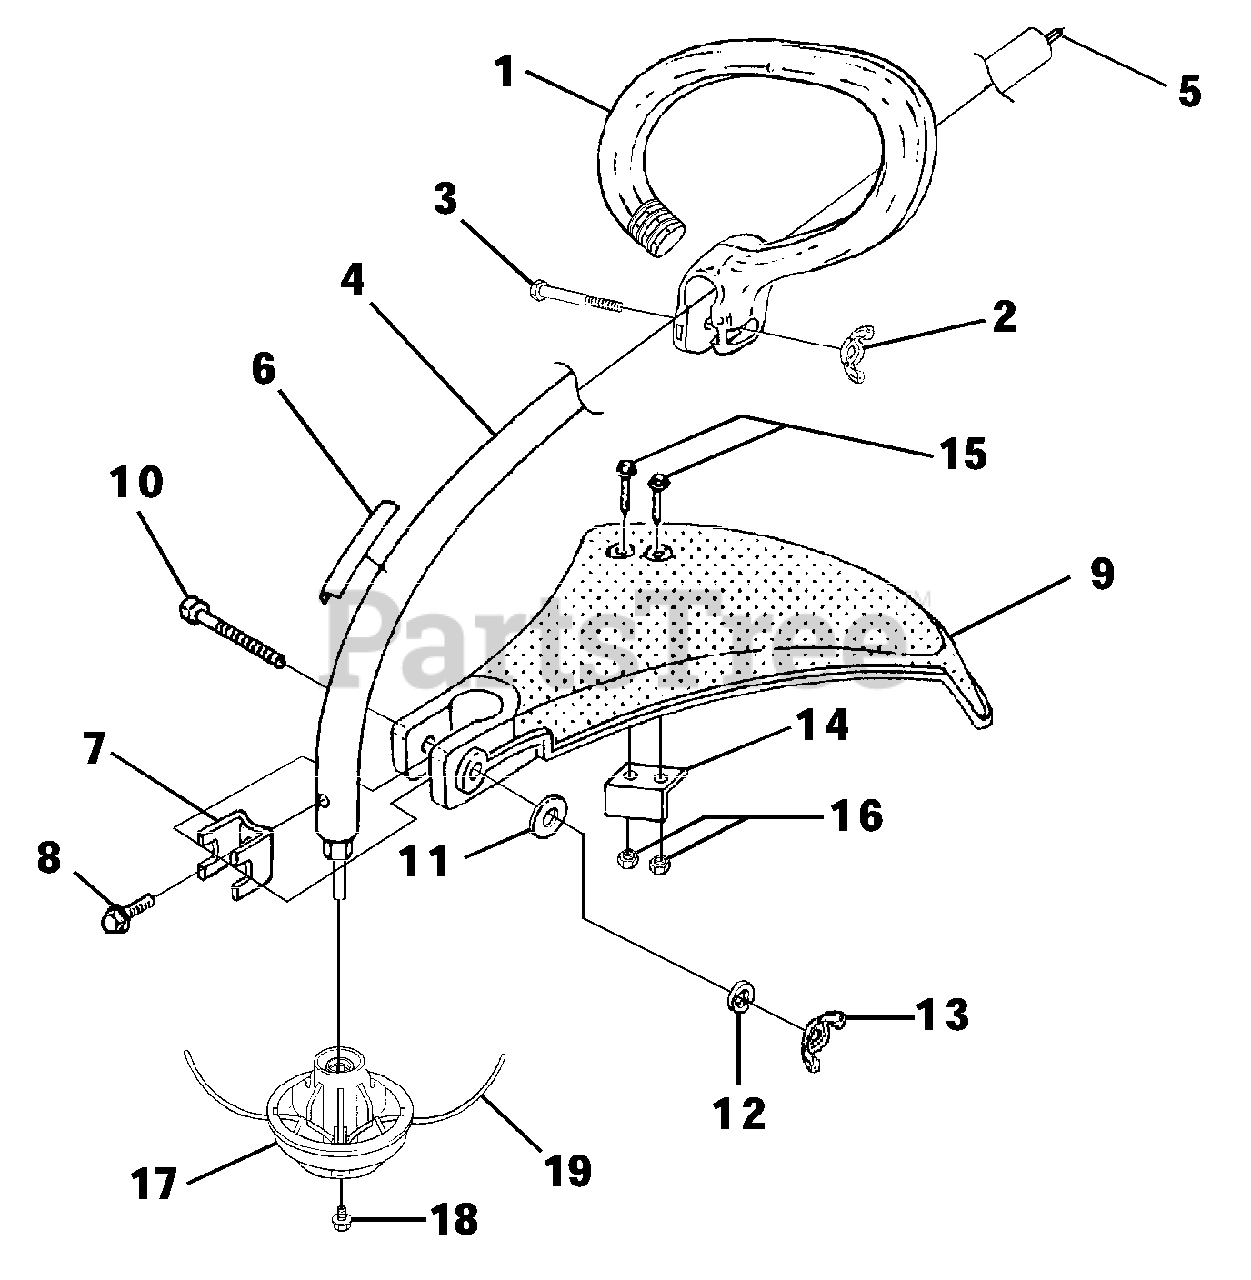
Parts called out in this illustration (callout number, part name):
1	HANDLE-Anti-Vibe
2	NUT-Wing, Washer Faced (1/4-20)
3	SCREW-Cap Hex Hd.
4	DRIVESHAFT HOUSING ASSY.
5	SHAFT-Flexible
6	DECAL-Warning
7	CLAMP
8	SCREW-Sems Hex Hd. (#10-24 X 3/8")
9	DEFLECTOR & BLADE KIT (55 Deg.)
10	SCREW-Cap Hex Hd. (10-24 X 2")
11	WASHER-Flat (1/4")
12	WASHER-Lock (1/4")
13	NUT-Wing, Washer Faced (1/4-20)
14	BLADE-Cut-Off
15	SCREW-Mech. Hex Hd. (10-24 X 7/8")
16	NUT-Hex (10-24)
17	STRINGHEAD-Pro-Cut w/line
18	SCREW-Stringhead Retainer
19	LINE-Replacement
